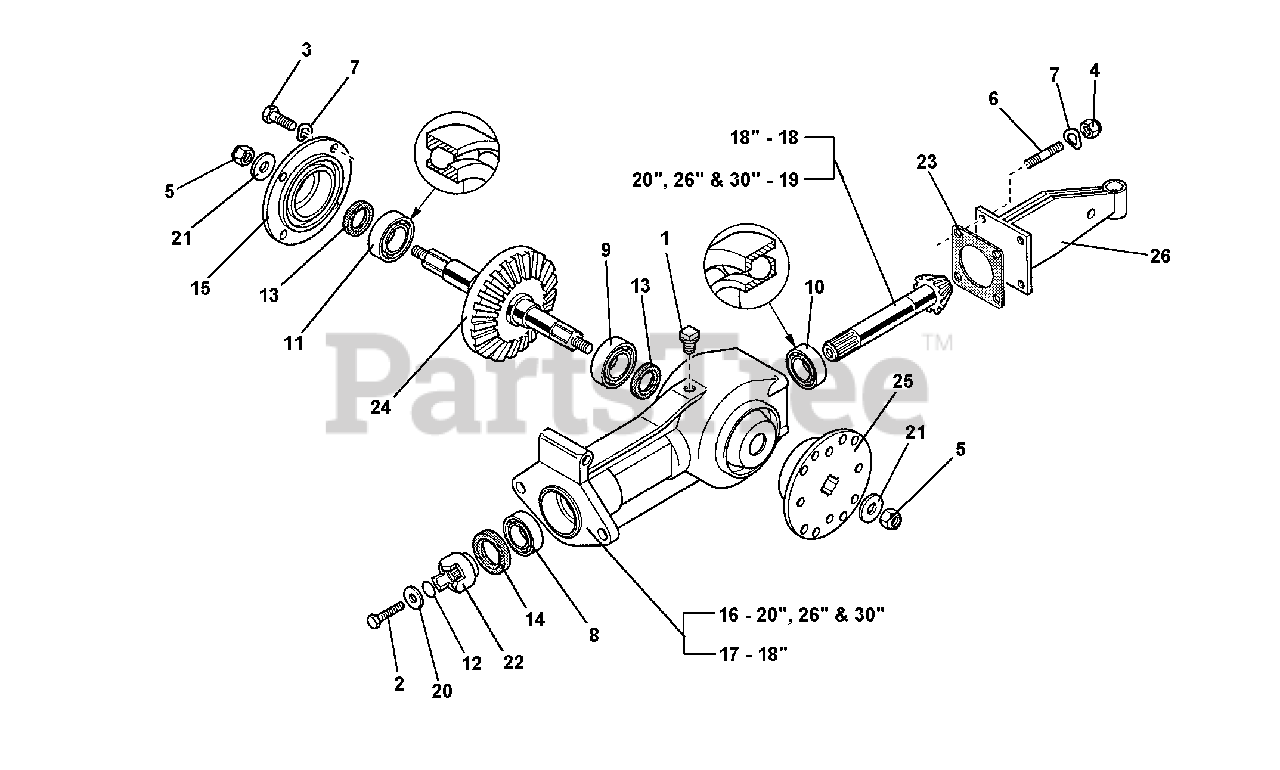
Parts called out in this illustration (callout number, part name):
2	SCREW, M6X20
3	SCREW, M8X25
4	NUT, SELF LOCKING, M8
5	NUT, SELF LOCKING, M14
6	STUD, M8X32X14X14
7	WASHER, LOCKING, M8.4
8	BEARING, M20X42X12
9	BEARING, M25X52X15
10	BEARING, M20X47X14
11	BEARING, M25X52X15
14	OIL SEAL, 28X42X7
16	GEAR CASE HOUSING
17	GEAR CASE HOUSING, 18" TILLER
18	PINION SHAFT, 18" TILLER
19	PINION SHAFT, 20" - 30" TILLER
22	PTO COUPLER
23	BACK COVER GASKET
24	TINE SHAFT AND GEAR
25	BLADE HOLDER FLANGE
26	REAR COVER FOR TILLER
27	GEARBOX COMPLETE 20", 26", 30"
28	GEARBOX COMPLETE 18"
